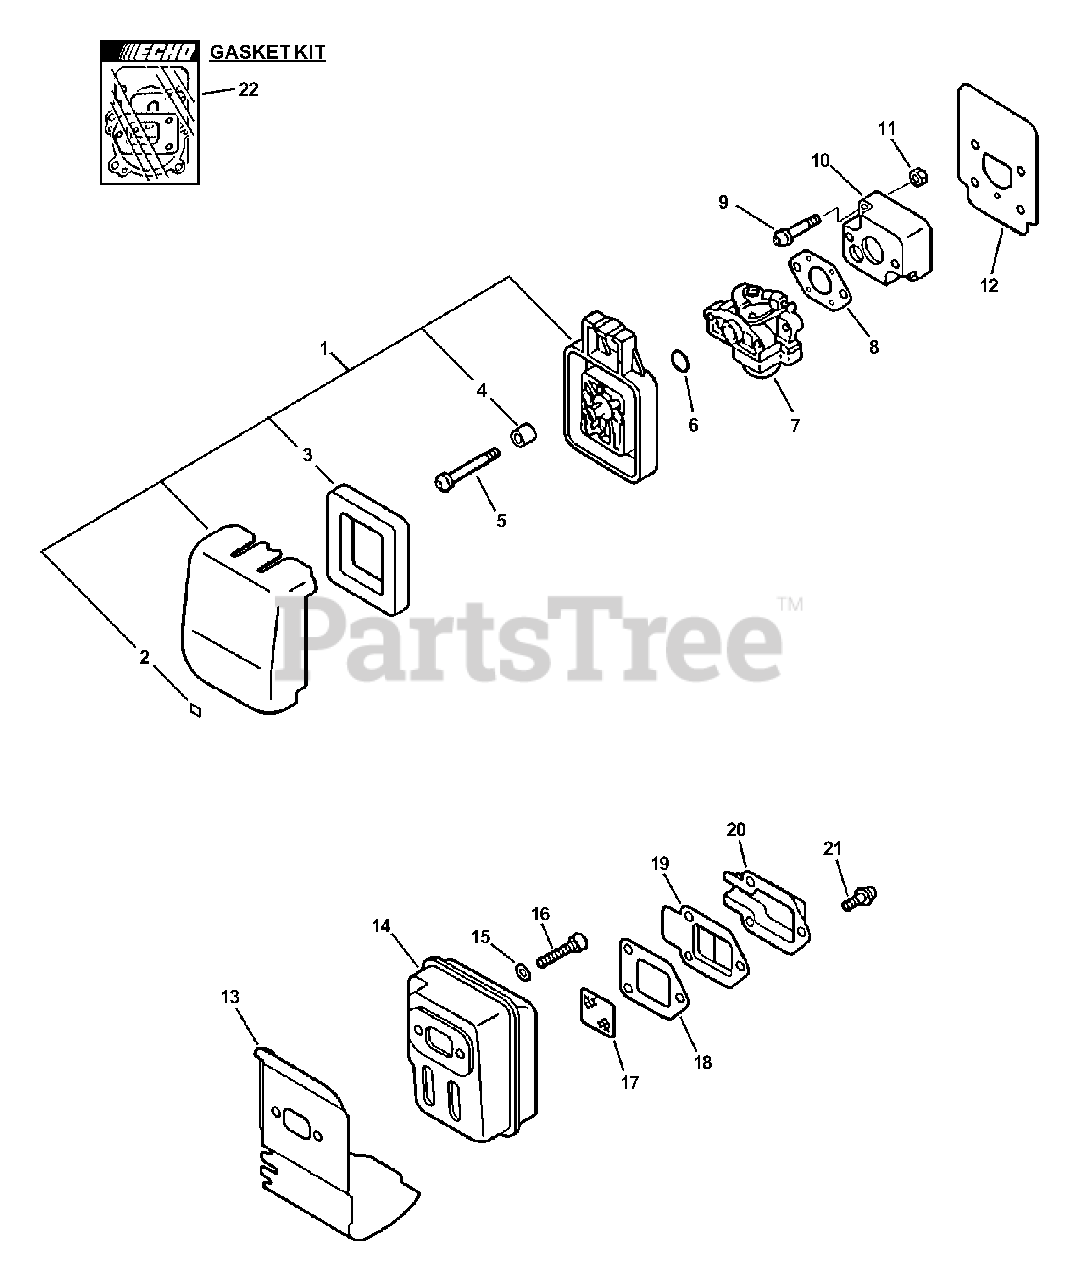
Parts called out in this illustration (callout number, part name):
1	AIR CLEANER ASSY
3	FILTER, AIR
4	SLEEVE
5	SCREW - 5X64
6	O-RING - 15
7	CARBURETOR WYL-180A
8	GASKET, INTAKE
9	SCREW - 5X20
10	INSULATOR, INTAKE
12	SHIELD, INTAKE
13	GASKET, EXHAUST
14	MUFFLER
15	WASHER - 5
16	SCREW - 5X55
17	SCREEN, SPARK ARRESTOR
18	GASKET, EXHAUST
19	GASKET, EXHAUST - INNER
20	GUIDE, EXHAUST - OUTER
21	SCREW - 4X10
22	GASKET KIT
